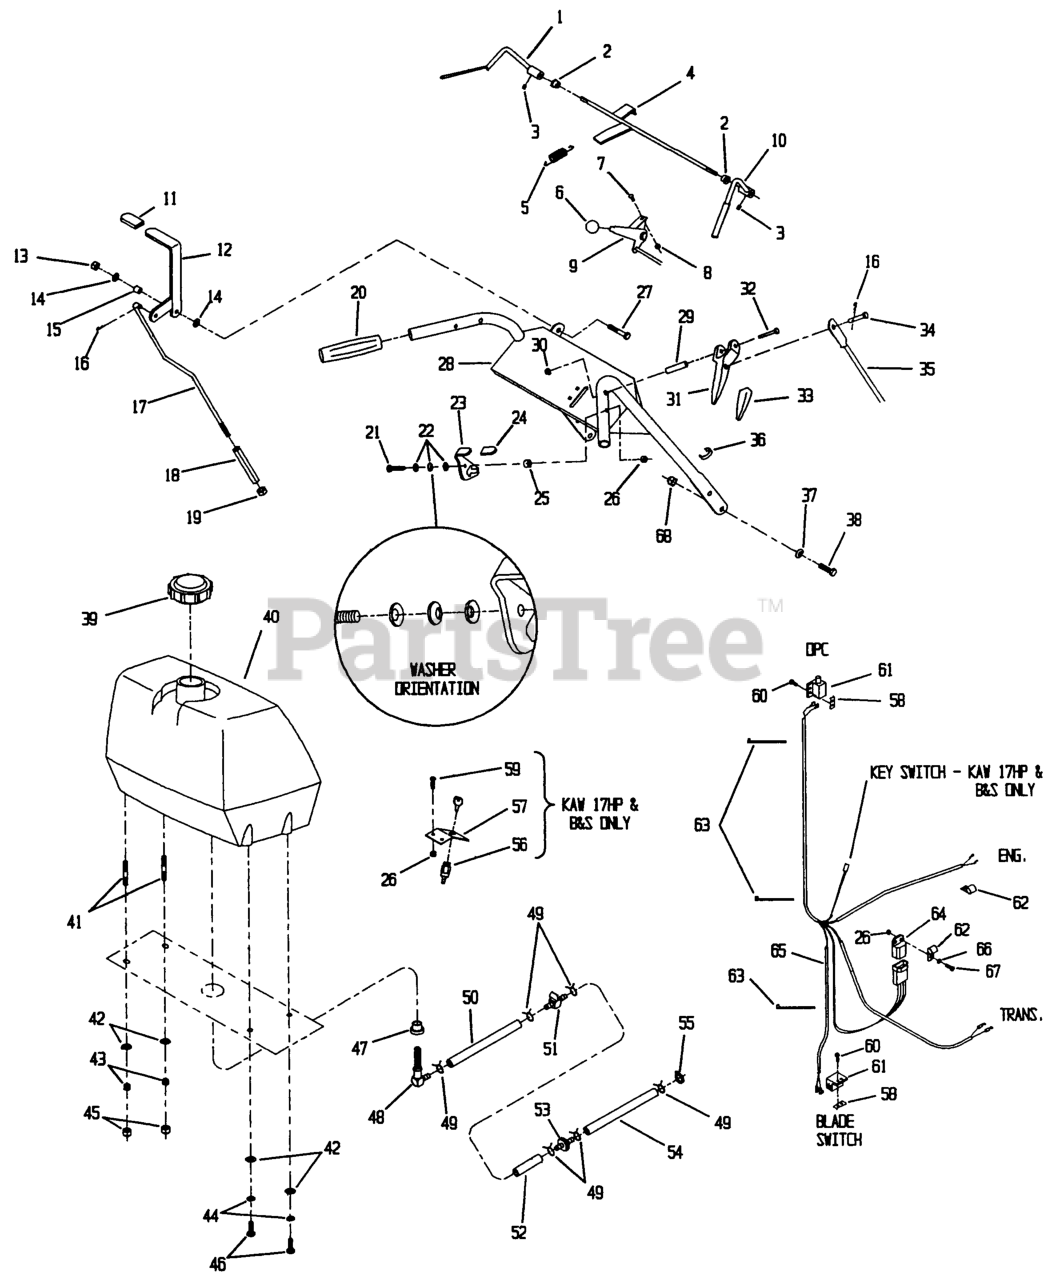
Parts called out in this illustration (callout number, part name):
1	LEVER-LH
2	BUSHING-NYLON
3	SCREW-SET
4	WLD,ROD OPC
5	SPRING-EXTENSION
6	KNOB-BALL
7	BOLT-CARR
9	CABLE,THROTTLE CONTROL
10	LEVER-RH
11	GRIP-LEVER
15	BUSHING-LEVER, LIFT
16	PIN-COTTER
17	LINKAGE,UPPER
18	TURNBUCKLE
22	WASHER-SPRING
24	GRIP-LATCH
29	PIN-ROLL
30	NUT-PUSH
31	DRIVE LEVER ASM
32	PIN-LEVER, DRIVE
33	GRIP-LEVER, DRIVE
34	PIN-CLEVIS
35	LINKAGE,DRIVE WHEEL
36	CLIP-CABLE
39	CAP-FUEL
41	STUD
43	SPRING-TANK, FUEL
44	WASHER-LOCK
48	ELBOW-TANK, FUEL
49	CLAMP
50	HOSE-FUEL
51	VALVE-FUEL
52	HOSE-LINE, FUEL
54	LINE-FUEL
55	CLAMP-HOSE
56	SWITCH & KEY (INCLUDES NU
58	PLATE-TAPPED
61	SWITCH-OPEN, NORMALLY
62	CLIP-LOOM
63	TIE-CABLE
64	MODULE-INTERLOCK
